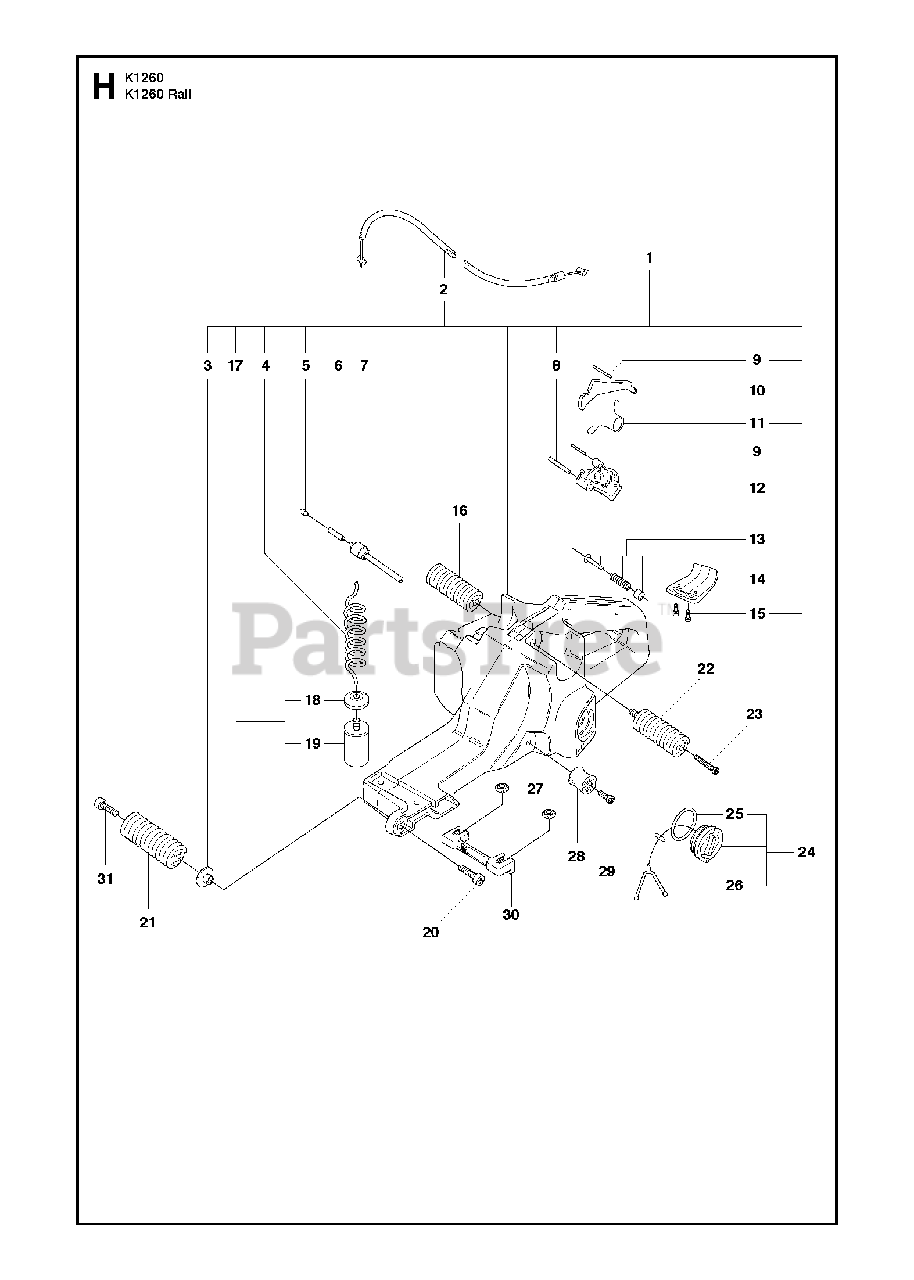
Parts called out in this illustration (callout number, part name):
1	TANK UNIT ASSYIncl. 1 - 15, 17
2	THROTTLE CABLE ASSY
4	FUEL HOSE
6	FUEL HOSE
7	TANK VENT
8	PARALLEL PIN
9	PARALLEL PIN
10	THROTTLE LOCKOUT
12	THROTTLE CONTROL ASSY
13	SPÄRRSTIFT RES
15	SCREW CRCSFT
16	ANTIVIBRATION ELEMENT
17	FUEL FILTERIncl. 18 - 19
20	SCREW ITXSCM
21	ANTIVIBRATION ELEMENT
22	ANTIVIBRATION ELEMENT
23	SCREW ITXSCM
24	TANK CAP ASSYIncl. 25 - 26
27	NUT
28	ANTIVIBRATION ELEMENT
29	SCREW ITXSCM
31	SCREW ITXSCM
